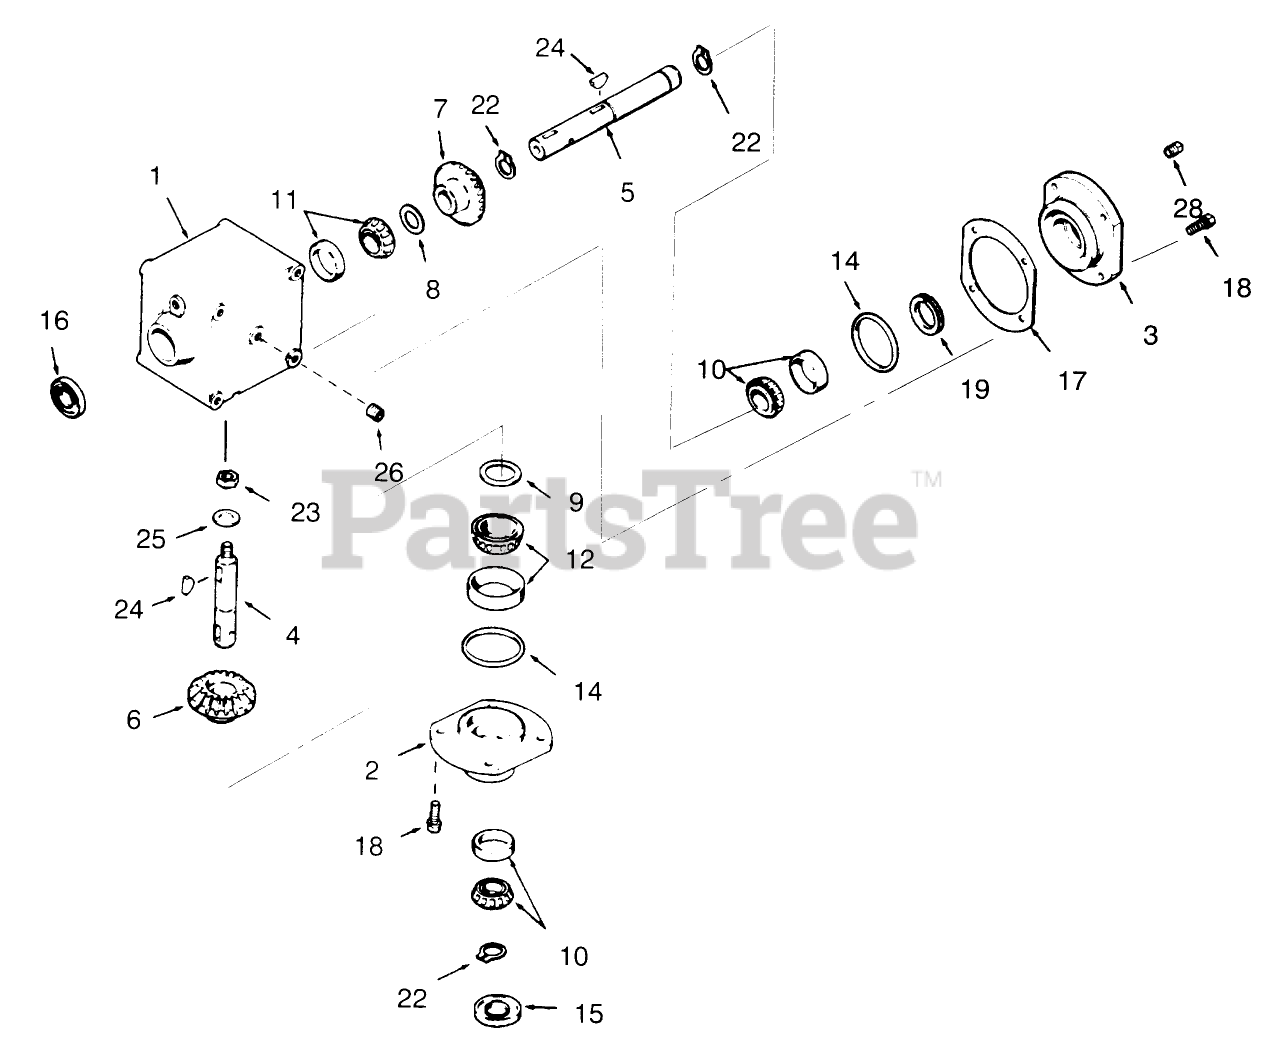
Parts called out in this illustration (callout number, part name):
1	Cap-Retainer
3	Cap-Retainer
4	Shaft-Input
5	Shaft-Output
6	Gear-Bevel 25T
7	Gear-Bevel 26T
8	Shim (1.5" OD x 1.016" ID x .002")
9	Shim (2" OD x 1.531" ID x .002")
10	Bearing & Cup Assembly
11	Bearing & Cup Assembly
12	Bearing & Cup Assembly
14	"O"Ring
15	Seal-Oil
16	Seal-Oil
17	Shim-Oil
18	Screw-Hex Hd.
19	Ring-Load
22	Ring-Retaining
23	Jam Nut
24	Key-Woodruff
25	Washer-Flat
26	Plug-Pipe
28	Plug-Pipe
